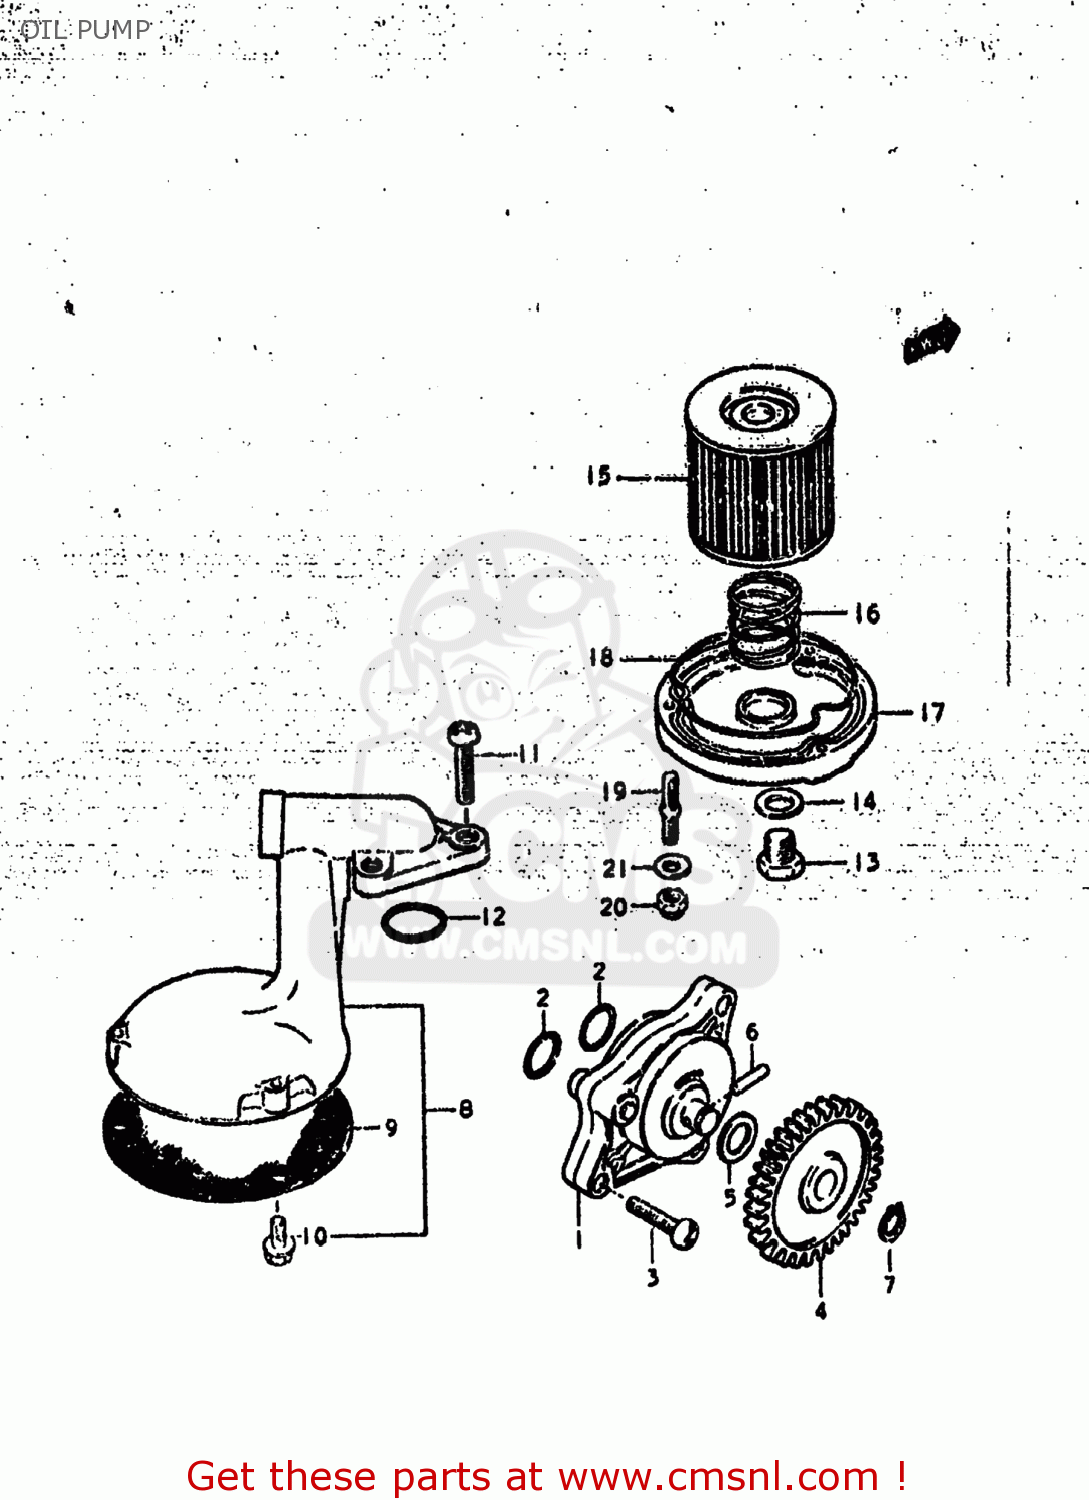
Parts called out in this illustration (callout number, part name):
1	PUMP ASSEMBLY,OIL
2	O RING(D:1.9,ID:13)
3	SCREW
4	GEAR,OIL PUMP DRIVEN
5	SHIM
6	PIN(4X15.8)
7	CIRCLIP
8	STRAINER,ENGINE OIL
9	NET
10	BOLT
11	SCREW
12	O RING(D:2.4,ID:15.8)
13	PLUG
14	GASKET(14X19.2X2) (NAS)
15	FILTER ASSY,ENGINE OIL
16	SPRING
17	CAP,OIL FILTER
18	O RING,OIL FILTER CHAMBER CAP
19	STUD 6X20
20	NUT
21	WASHER
